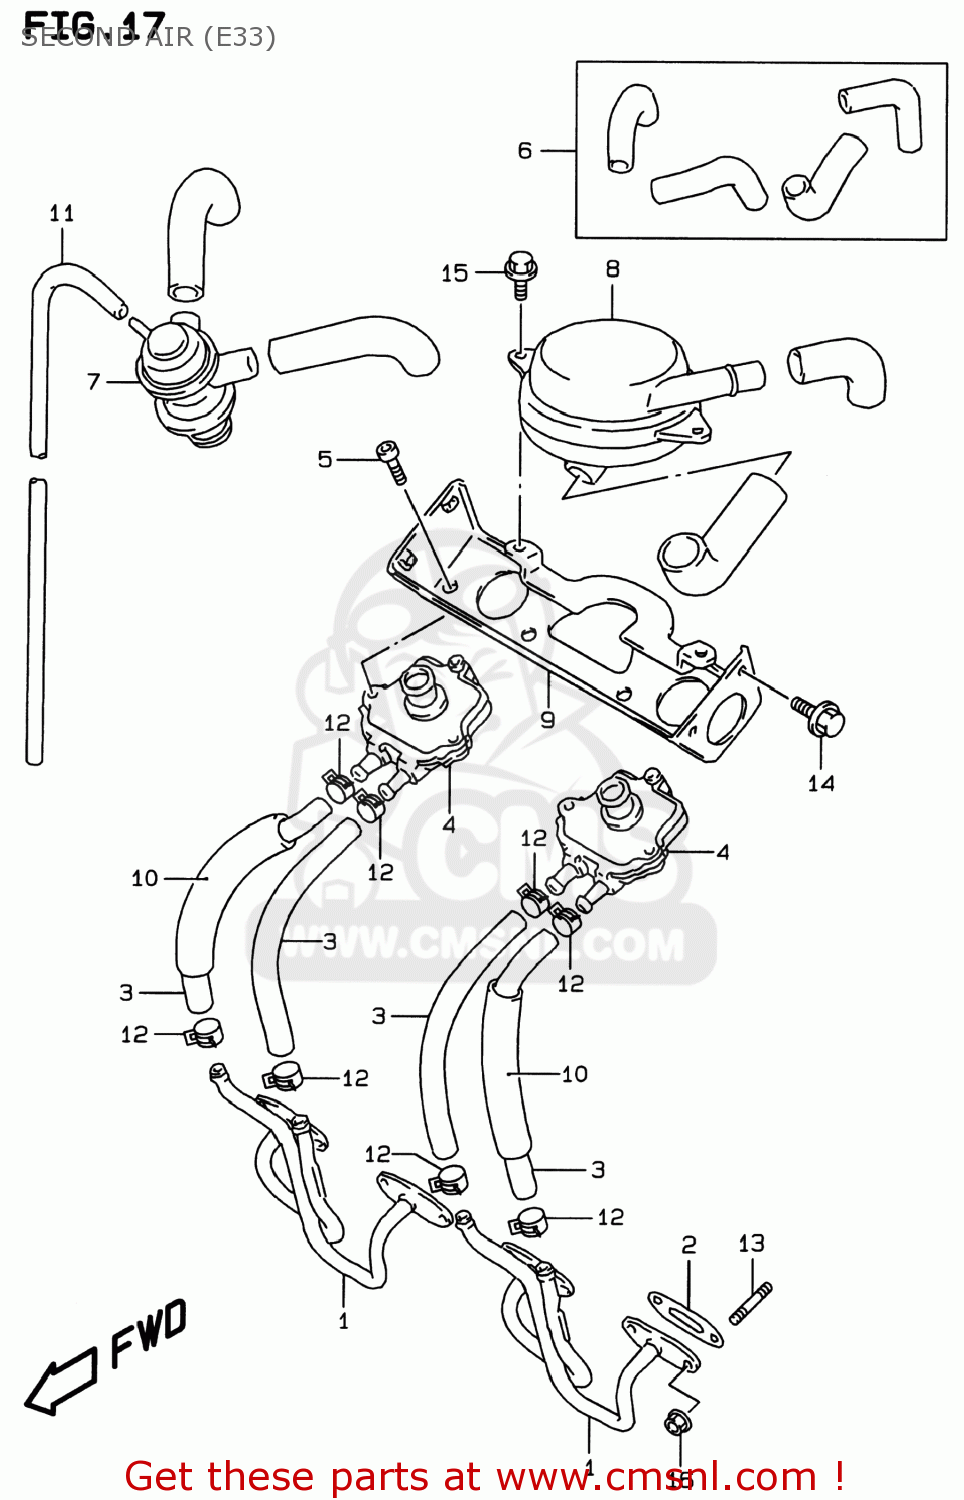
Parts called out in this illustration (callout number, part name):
1	PIPE,2ND AIR,L
2	GASKET,SECOND AIR PIPE (NAS)
3	HOSE,SECOND AIR REED VALVE
4	VALVE ASSY,2ND AIR REED
5	BOLT
6	HOSE SET,SECOND AIR
7	VALVE ASSEMBLY,SECOND AIR SWITCH
8	CLEANER ASSEMBLY,SECOND AIR
9	BRACKET,SECOND AIR
10	PROTECTOR,REED VALVE
11	HOSE(4.5X8.5X600)
12	CLIP
13	STUD BOLT
14	BOLT,STRANGER
15	BOLT
16	NUT
